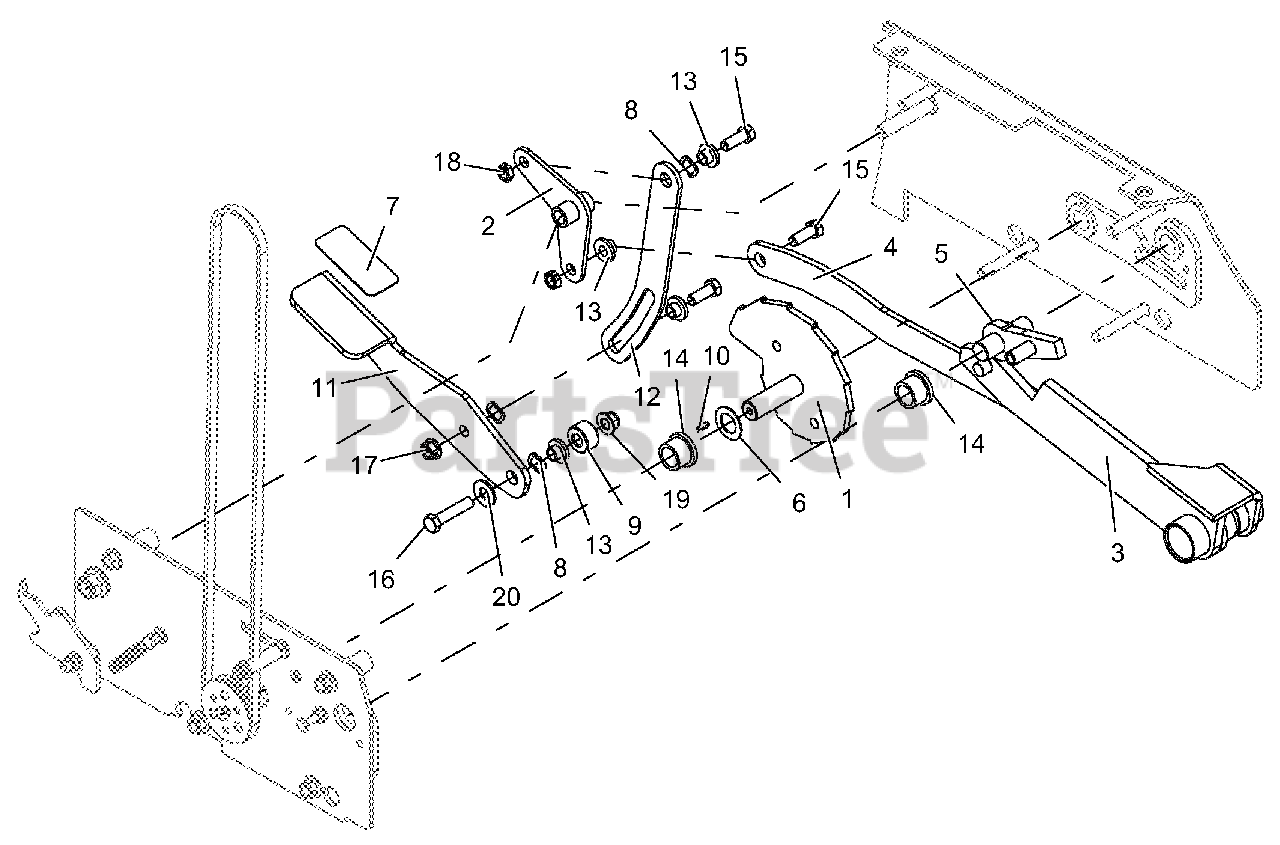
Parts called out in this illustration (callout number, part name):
1	WLDMT, HEIGHT OF CUT
2	WLDMT, REAR PIVOT - BLACK
3	WLDMT, CAM CONTACT - BLACK
4	WLDMT, DECK LIFT LINK - BLACK
5	WLDMT, TRAILER LOCK
6	BUSHING, MACH .75 x 1.25 x .048
7	GRIP, PEDAL 1.50 x 3.00
8	WAVE WASHER .531 x .781 x .125 FH
9	SPACER, .437 x 1.00 x .58 SMLS
10	KEY, .125 SQ. x .50
11	PEDAL, DECK LIFT
12	ARM, PEDAL - BLACK
13	BSHG, FLG .385 x .500 x .875 x .406
14	BUSHING, .750 x 1.00 x .750
15	BLT-HEX .38-16 x 1.00 GR5 YWZC
16	BLT-HEX .38-16 x 1.75 GR5 YWZC
17	NUT, LK-CTR-FLG .38-16 YWZC
18	@NUT-LK-CTR-JAM .375-16 YWZC
19	NUT-LK-NYL-FLG .38-16 YWZC
20	WSHR-FL-STL .438 x 1.00 x .083 YWZC
